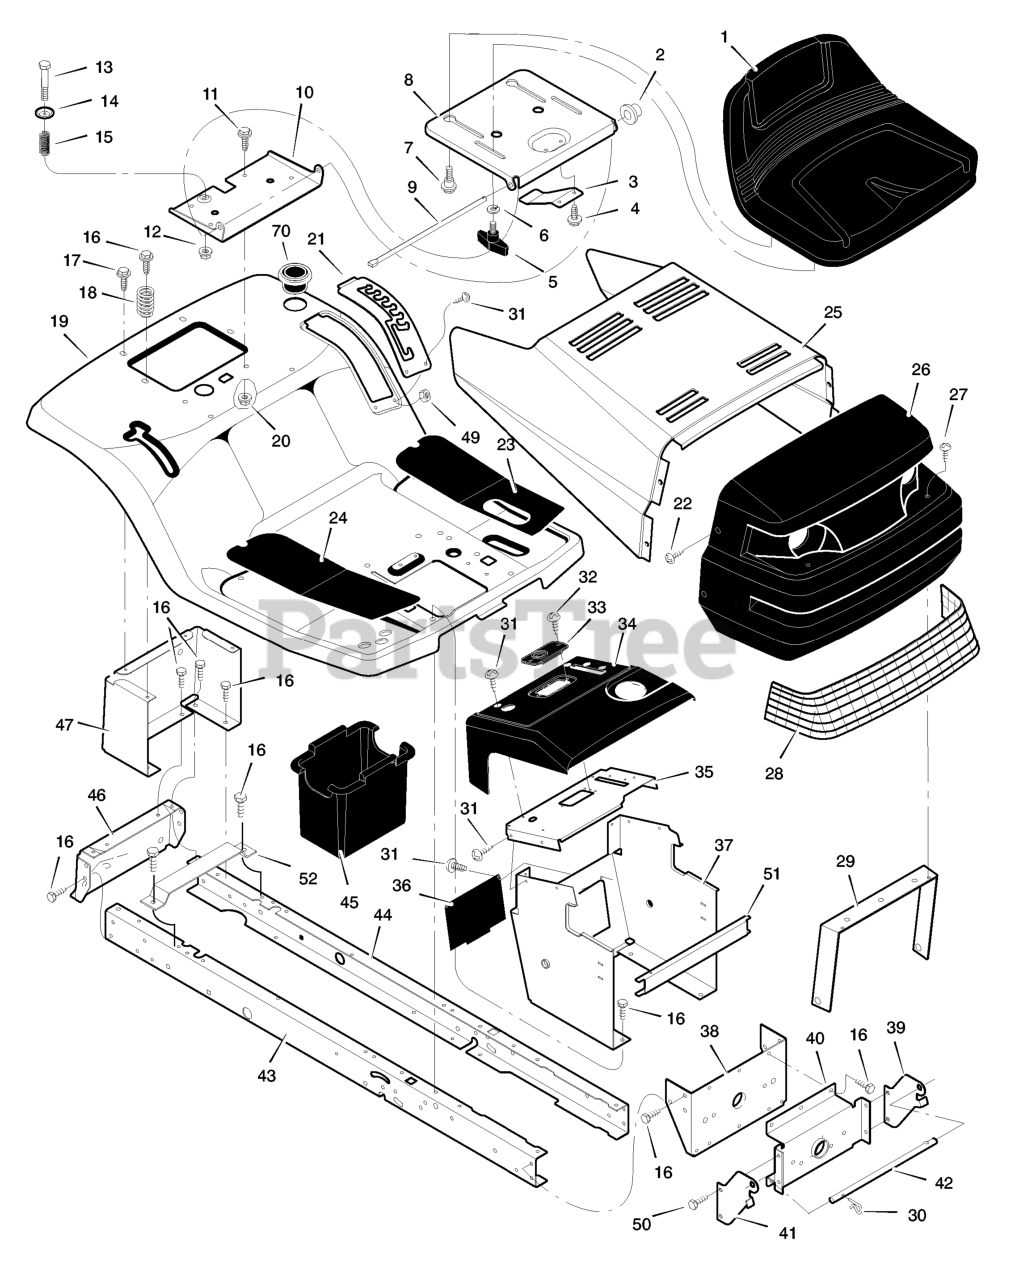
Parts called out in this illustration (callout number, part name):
2	Cap, Push On
5	Bolt, Wing
6	Washer
7	Bolt, Shoulder
8	Support, Seat
9	Rod, Pivot
10	Bracket, Pivot
11	Bolt
13	Bolt, Shoulder
15	Spring
19	Deck, Seat
20	Nut
21	Plate, Index
23	Mat, Left
24	Mat, Right
26	Grille Assembly
27	Screw
28	Lens
29	Brace, Grille
30	Pin, Hair
31	Screw
33	Bearing, Steering
35	Plate, Dash
36	Panel, Access
37	Support, Dash
38	Bracket, Rear Hanger
39	Support, Left Grille
40	Axle, Hanger
41	Support, Right Grille
42	Rod, Pivot
43	Frame, Right
44	Frame, Left
45	Container, Battery
46	Plate, Hitch
47	Panel, Rear
52	Support, Battery
70	Holder, Cup
